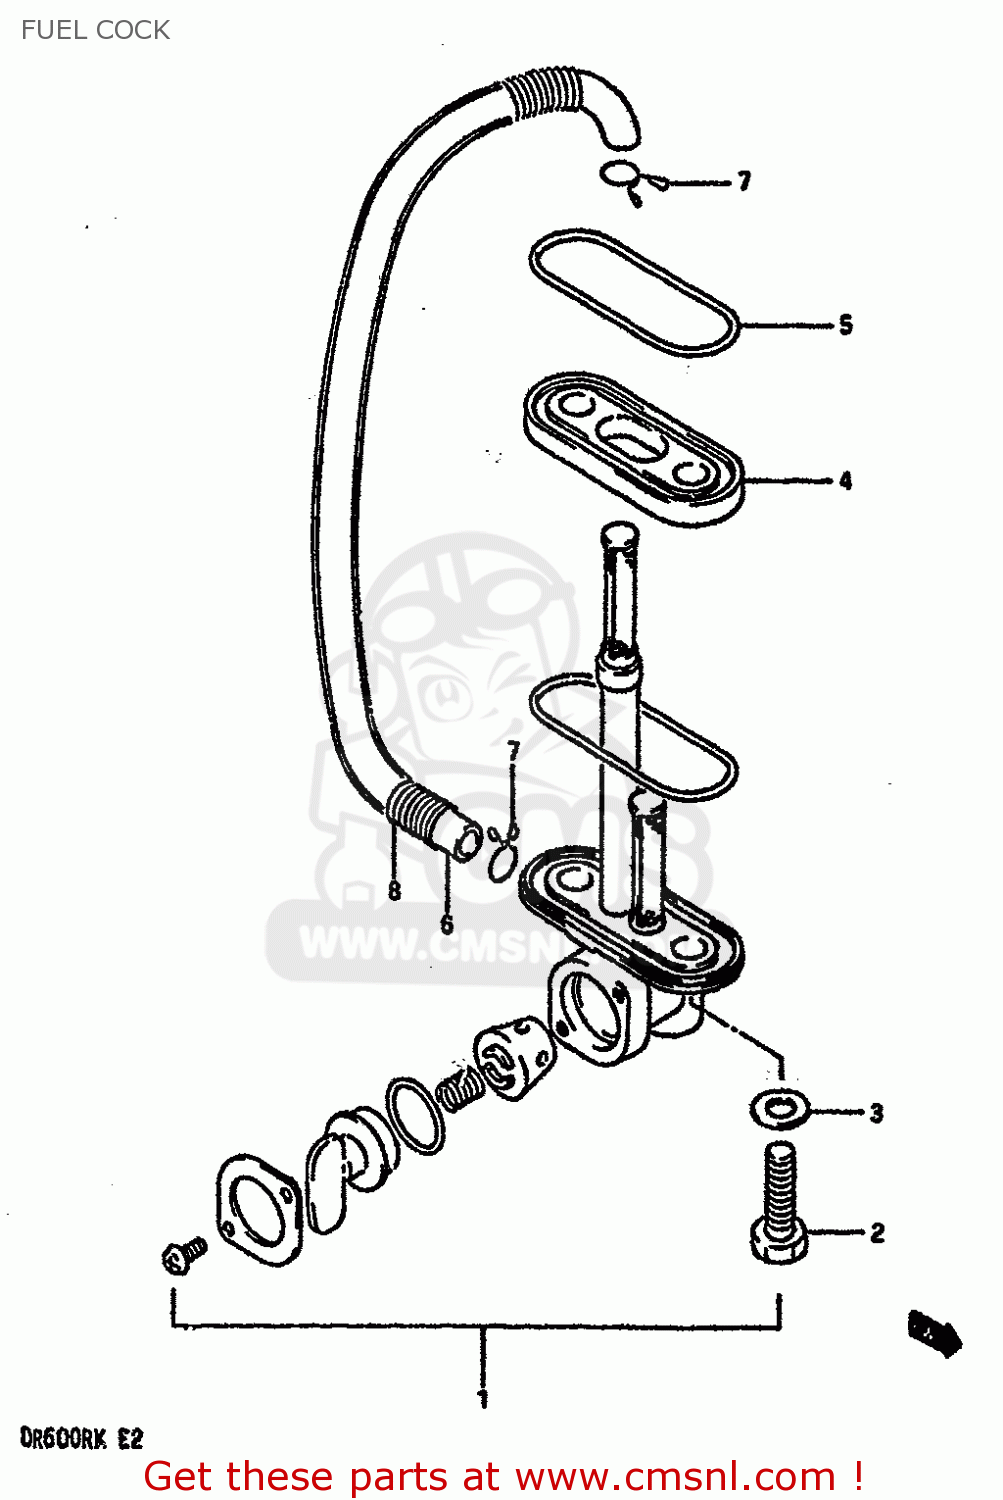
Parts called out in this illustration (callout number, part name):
1	COCK ASSY,FUEL
2	BOLT(6X20)
3	GASKET
4	SPACER,FUEL COCK
5	GASKET,FUEL COCK (NAS)
6	HOSE
7	CLIP
8	SPRING
